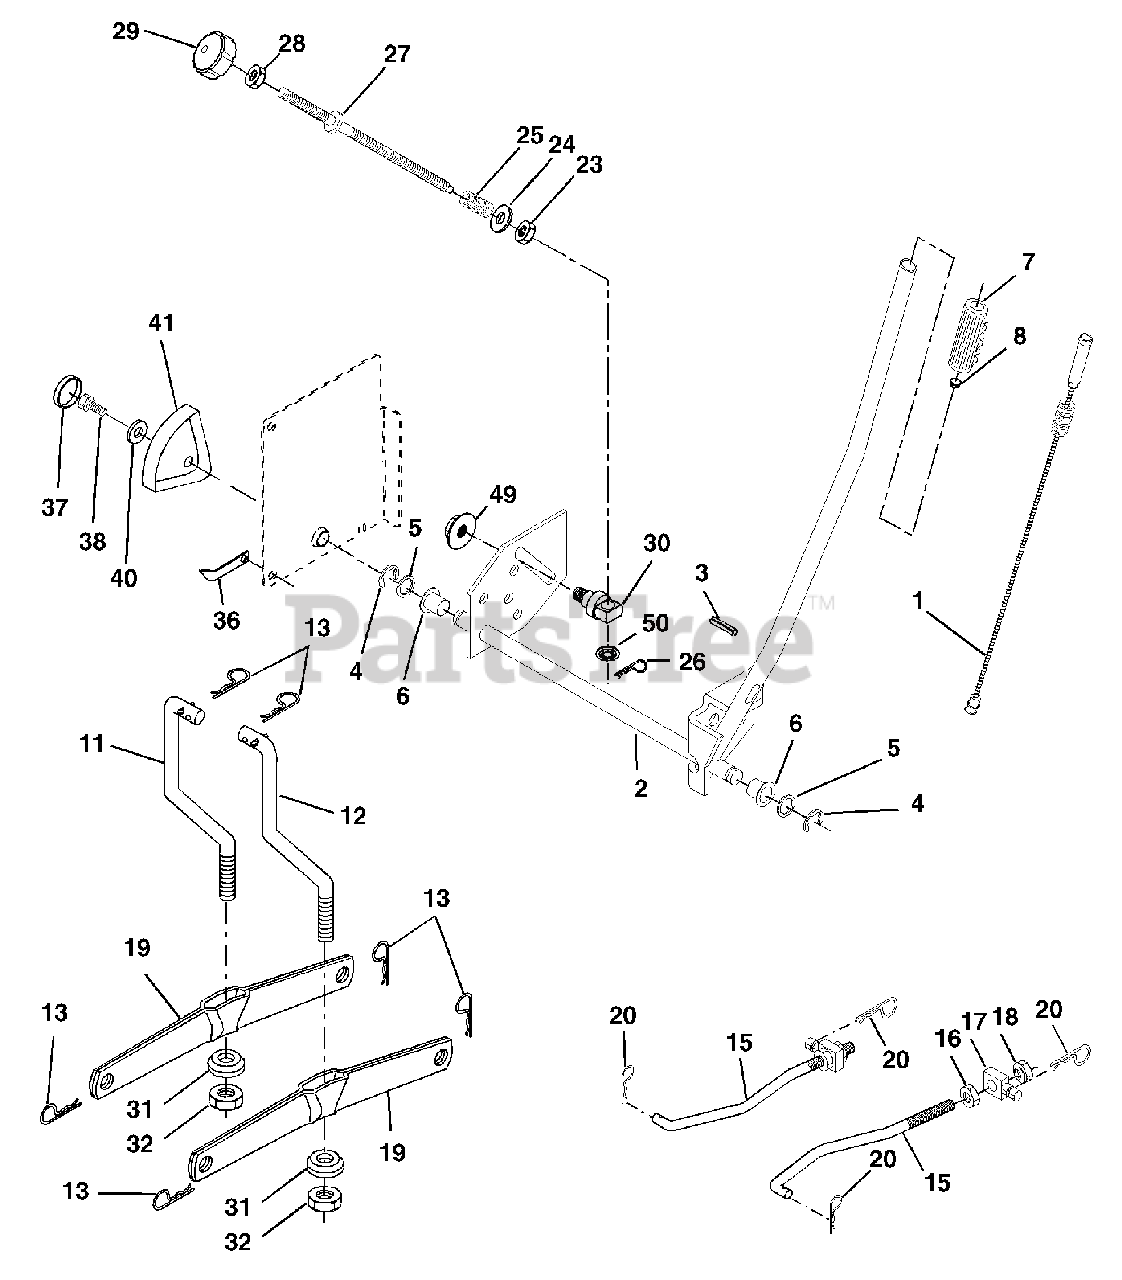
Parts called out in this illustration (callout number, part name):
1	Wire Asm Inner/Sprg W/plunger
2	Shaft Asm Lift RH w/Inf
3	Pin Groove
4	E Ring #5133-62
5	Washer 21/32 X 1 X 21 Ga
6	Bearing Nylon Blk 629 Id
7	Grip Handle
8	Button Plunger
11	Link Lift LH
12	Link Lift RH
13	Retainer Spring
15	Link Suspension Front
16	Nut Jam Hex 1/2-13 Unc
17	Trunnion Front Susp.
18	Nut Lock w/Wsh 1/2-13unc
19	Arm Asm Suspension Mower
20	Retainer Spring
23	Nut Special
24	Washer 13/32 X 5/8 X 16 Ga
25	Spring
26	Retainer Clip
27	Rod Adj Lift
28	Nut Hex Jam 3/8-16 Unc
29	Knob Inf 3/8-16 Unc Blk W/sym
30	Trunnion Infin Height
31	Lift Pivot Bearing
32	Nut Crownlock 3/8-24
36	Pointer Height Indicator
37	Plug Hole Blk 1.485/1.515 Dia.
38	Screw 5/16-18 x 1
40	Washer 11/32 x 1-1/2 10 Ga.
41	Indicator Height STLT
49	Nut Hex Flange Lock
50	Nut PUsh Phos & Oil
